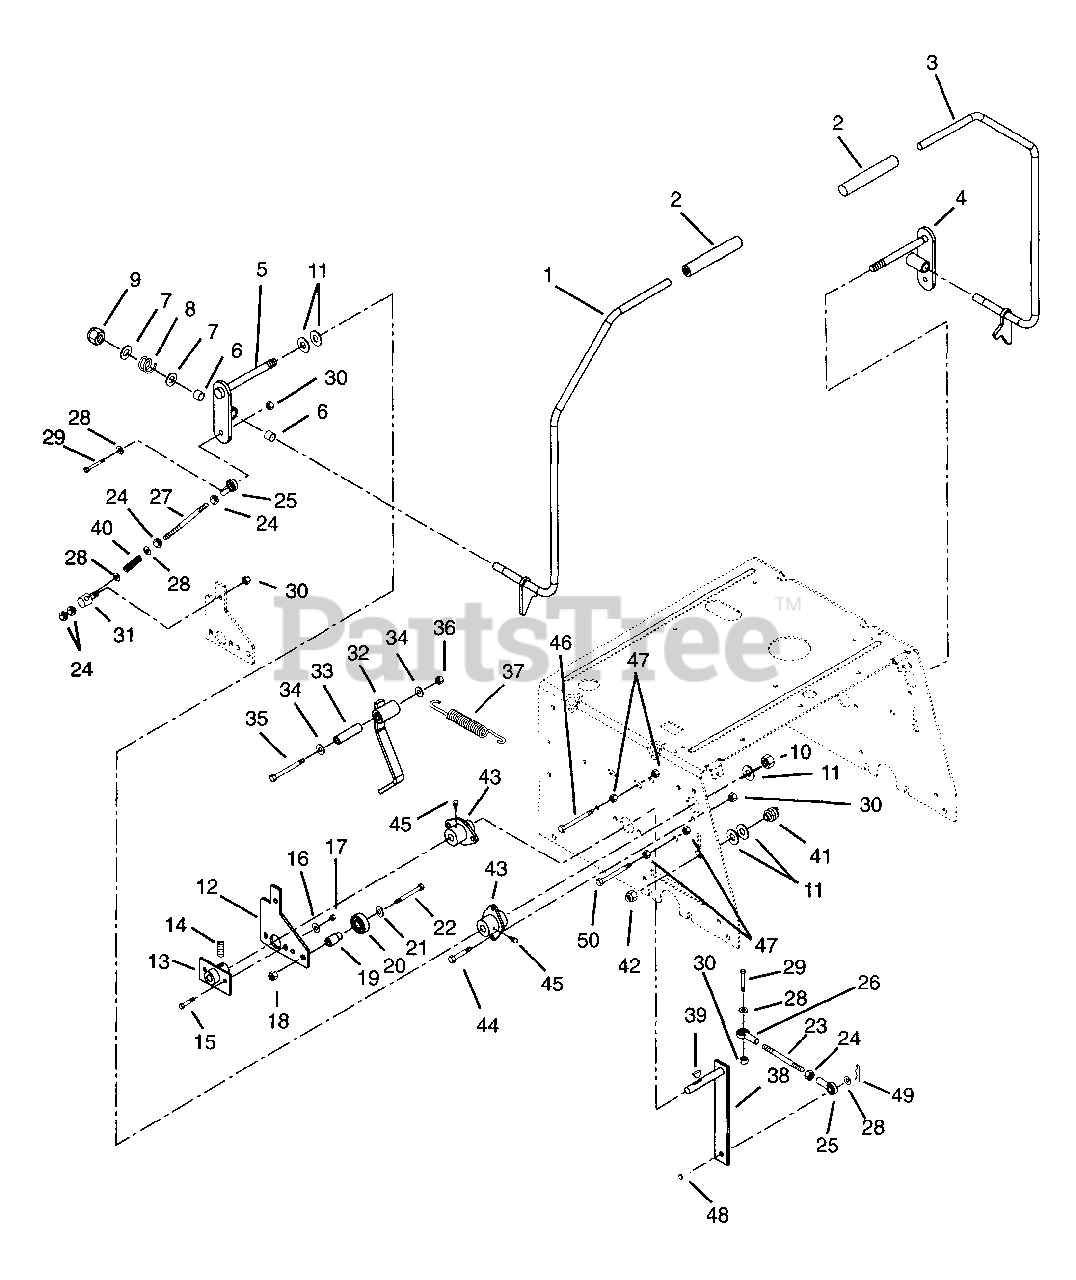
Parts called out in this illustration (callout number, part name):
1	RH STEER-CONTROL LEVER
3	LH STEER-CONTROL LEVER
4	CONTROL WELDMENT LH
5	CONTROL WELDMENT RH
6	BUSHING, NYLON .5 X .62 X .5LG
7	WASHER, PLASTIC .12X.53.1.12
8	SPRING, COMPRESSION
9	NUT-LK-CTR-JAM .50-13 YWZC(ND)
10	NUT-LK-NYL .50-20 PL(ND)
11	WSHR-FL-STL.563X1.37X.109PL
12	ARM,SPEED CONTROL
13	ARM, SPEED CONTROL
14	SCR-SET .25-20X.38 SKHCUP OH
15	BLT-HEX .25-20X.75 PL GR5
16	WSHR-FL-STL.281X.62X.065 PL
17	NUT-LK-NYL .250-20 PL
18	NUT-LK-NYL .375-16 PL
19	HUB, BRG. MOUNT
20	BRG-BALL .500X1.375X.437
21	WSHR-FL-STL.406X.812X.065PL
22	BLT-HEX .38-16X2.00 PL GR5
23	ROD TRANS CONTROL RH
24	NUT-HEX .312-24 PL
25	ROD END, 5/16 RH - FEMALE
26	ROD END, 5\16 LH - FEMALE
28	WSHR-FL-STL.344X.688X.065PL
29	BLT-HEX .31-18X1.25 PL GR5
30	NUT-LK-NYL.312-18 PL
31	PIVOT, ROD
32	WLDM'T, NEUTRAL DETENT
33	BUSH.,S.385X.610X1.80 ST
34	WSHR-FL-STL.406X.812X.065PL
35	BLT-HEX .38-16X2.75 PL GR5
36	NUT-LK-NYL .375-16 PL
37	SG-TENS .085X.60X5.13 WLD8.3
38	WLDMNT, PUMP CONTROL
39	KEY-WDRF .125X.75
40	SG, VARIBLE RATE
41	SWITCH, NEUTRAL START N.O.
42	NUT-STAMPED .56-18
43	BUSHING, FLANGED
44	BLT-HEX .31-18X1.00 PL GR5
45	FTG-LUBE .25-28X.256 YWZC
46	BLT-HEX .38-16X3.00
47	NUT-HEX .375-16
48	PIN-CLEV .312X.822 HDND PL
49	PIN-HAIR INT .08X.18X1.18
50	BLT-HEX .38-16X2.75 PL GR5
